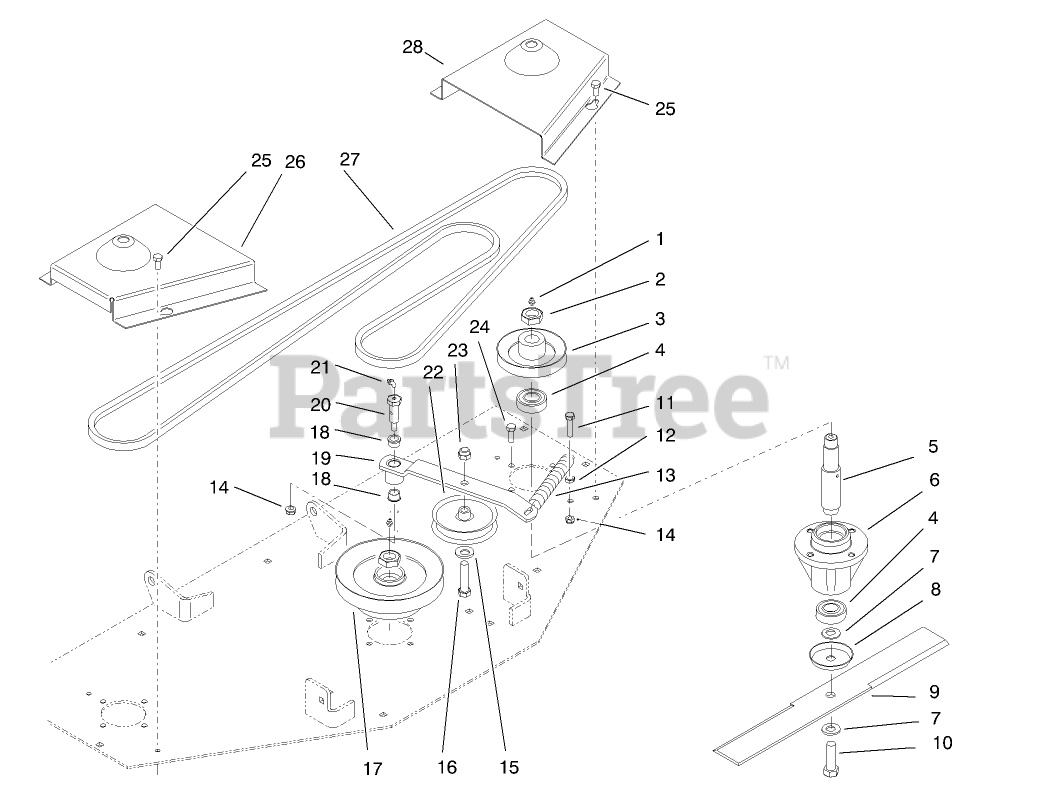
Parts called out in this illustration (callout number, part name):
1	FITTING-GREASE
2	NUT-LOCK, NI
3	PULLEY-PTO
4	BEARING-BALL
5	SHAFT - SPINDLE
6	HOUSING - SPINDLE
7	WASHER-SPECIAL
8	CUP-SPINDLE
9	BLADE
10	SCREW-HH
11	SCREW-HH
12	NUT-JAM
13	SPRING-EXTENSION
14	NUT-LOCK, NI
15	WASHER-FLAT
16	SCREW-HH
18	BUSHING
19	ARM-IDLER
20	BOLT-SHOULDER
21	FITTING-GREASE, 90 DEG
22	PULLEY-IDLER
23	NUT-LOCK, NI
24	SCREW-HH, LOCK
25	SCREW-HWH, TAPTITE
26	COVER-BELT, RH,
27	BELT-V DECK
28	COVER-BELT,LH,
